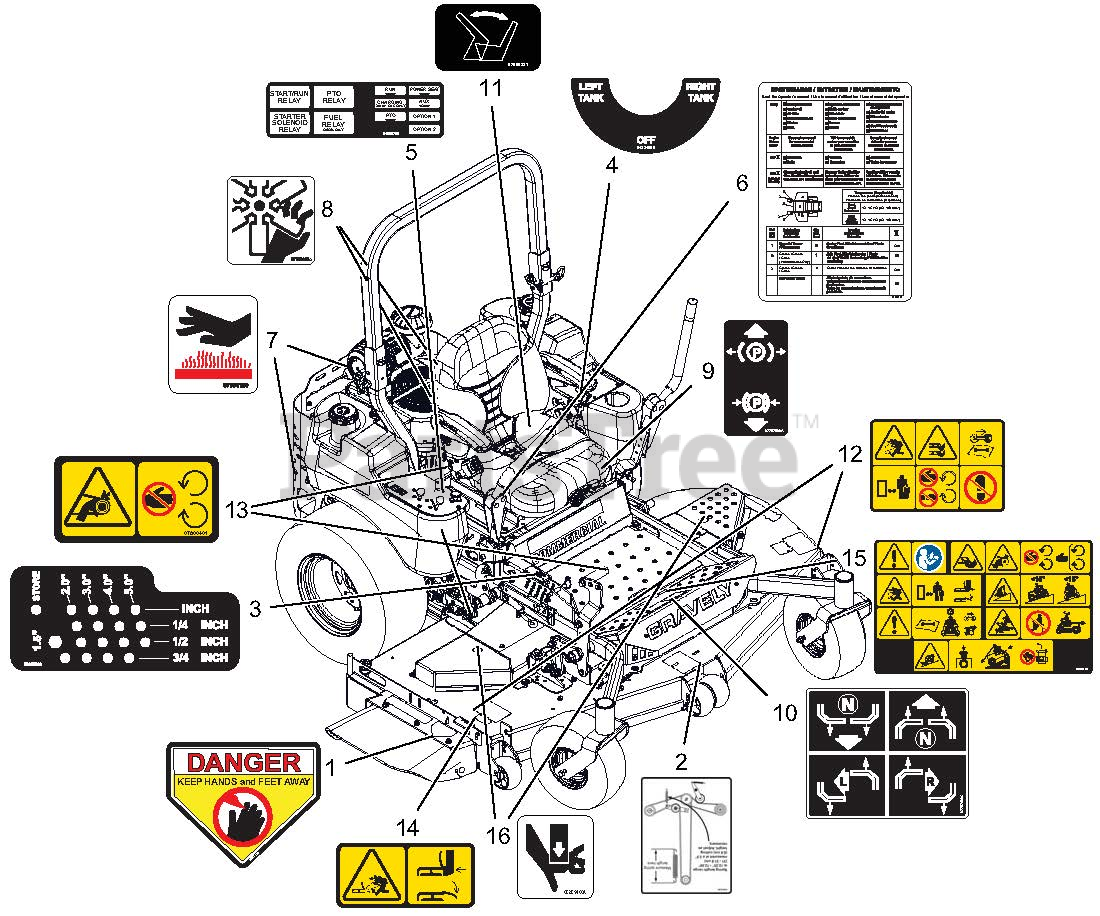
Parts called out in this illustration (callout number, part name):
1	DECAL, DANGER
2	DECAL, BELT DIAGRAM
3	DECAL, HEIGHT OF CUT
4	DECAL, FUEL VALVE
5	DECAL, FUSE BOX
6	DECAL, MAINTENANCE
7	DECAL, HOT SURFACE
8	DECAL, DANGER FAN
9	DECAL, PARKING BRAKE LEVER
10	DECAL, INSTRUCTIONAL-STEERING
11	DECAL - SEAT RELEASE
12	DECAL, SAFETY - MOWER DECK
13	DECAL, SAFETY - GUARDING
14	DECAL, SAFETY - DECK GUARDING
15	DECAL, MAIN SAFETY
16	DECAL, PINCH POINT
